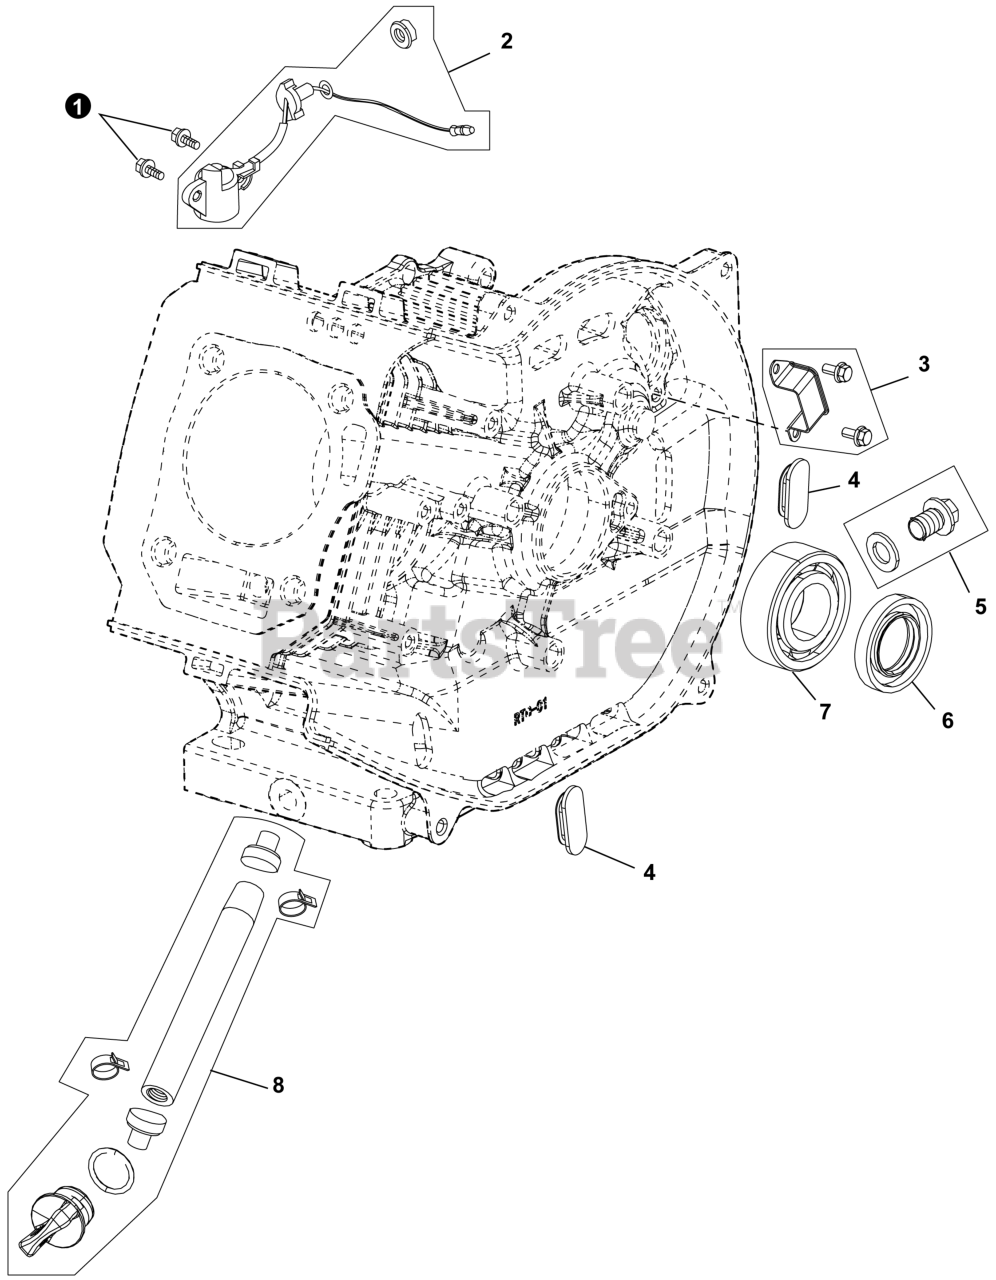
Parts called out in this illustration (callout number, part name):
2	SENSOR, ENGINE OIL
3	CLAMP, LEAD WIRE
4	PLUG, END
5	PLUG, OIL DRAIN
6	SEAL, OIL
7	BEARING, CRANKSHAFT
8	ASSY., OIL DRAIN TUBE
